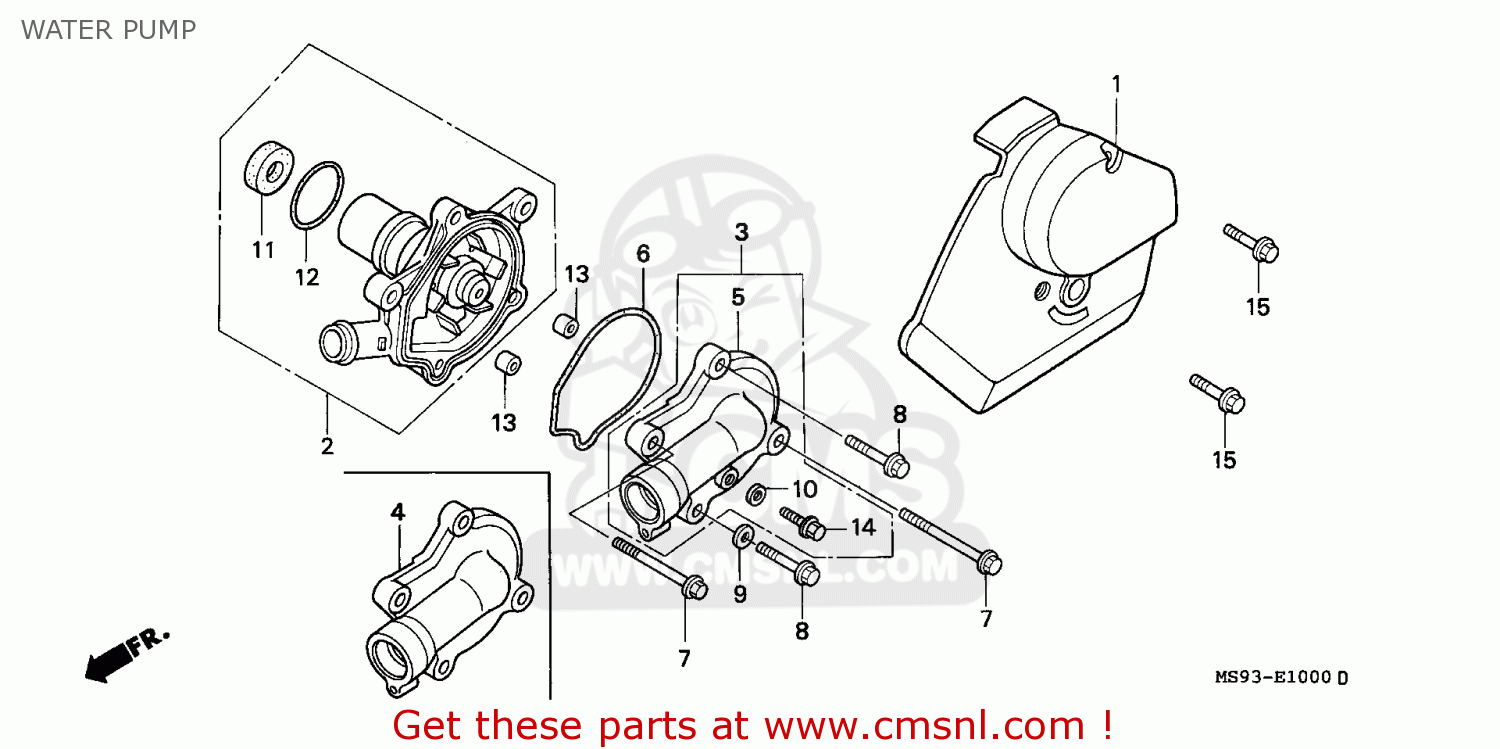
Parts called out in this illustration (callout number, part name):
1	COVER,L.CRANKCASE
2	PUMP COMP.,WATER
4	COVER,WATER PUMP
6	GASKET,W-PUMP COV
7	BOLT,SPECIAL,6X45
8	BOLT,SPECIAL,6X25
9	WASHER,11M/M
11	OIL SEAL,12X28X7
12	O-RING 32.95X2.62
15	BOLT,FLANGE,6X22
